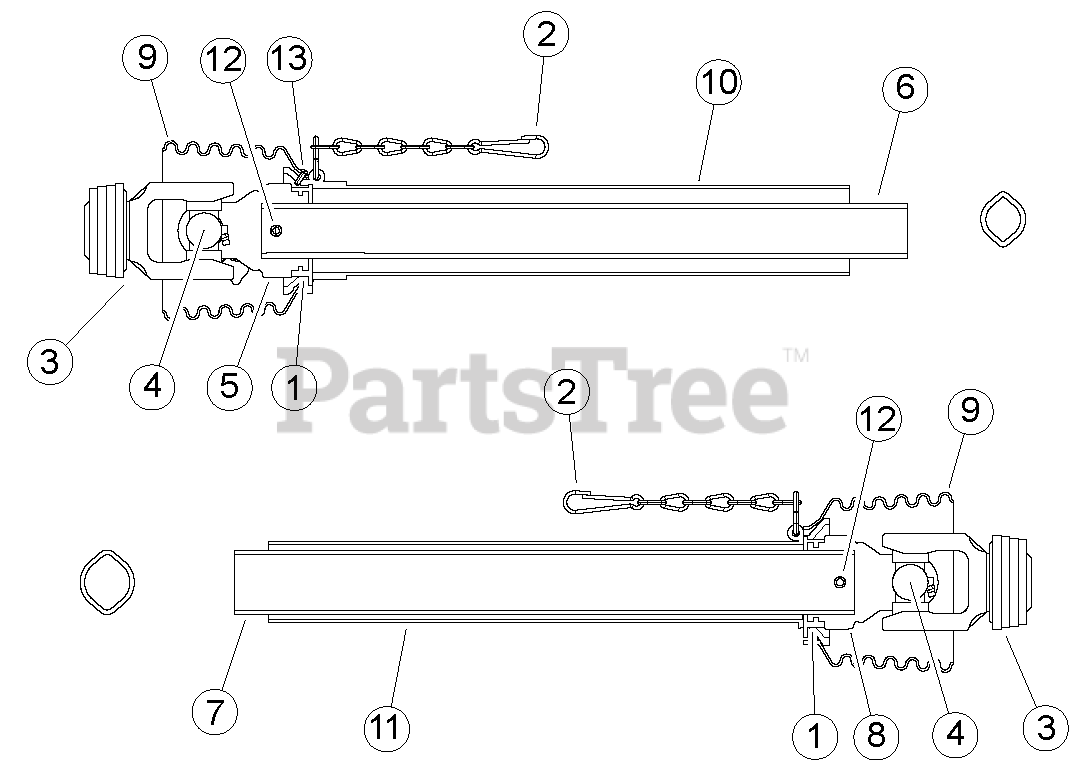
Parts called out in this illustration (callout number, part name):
1	RING, SC15 BEARING
2	CHAIN, SAFETY
3	YOKE, 1-3/8-6 SPLINGE ASGE
4	KIT, CROSS & BEARING
5	YOKE, INBOARD 0V
6	PROFILE, INNER 0V
7	PROFILE, OUTER 1
8	YOKE, INBOARD 1
9	CONE, 4 RIB
10	GUARD, TUBE OUTER
11	GUARD, TUBE INNER
12	PIN, 10 X 65 SPRING
13	SCREW, WS365344
